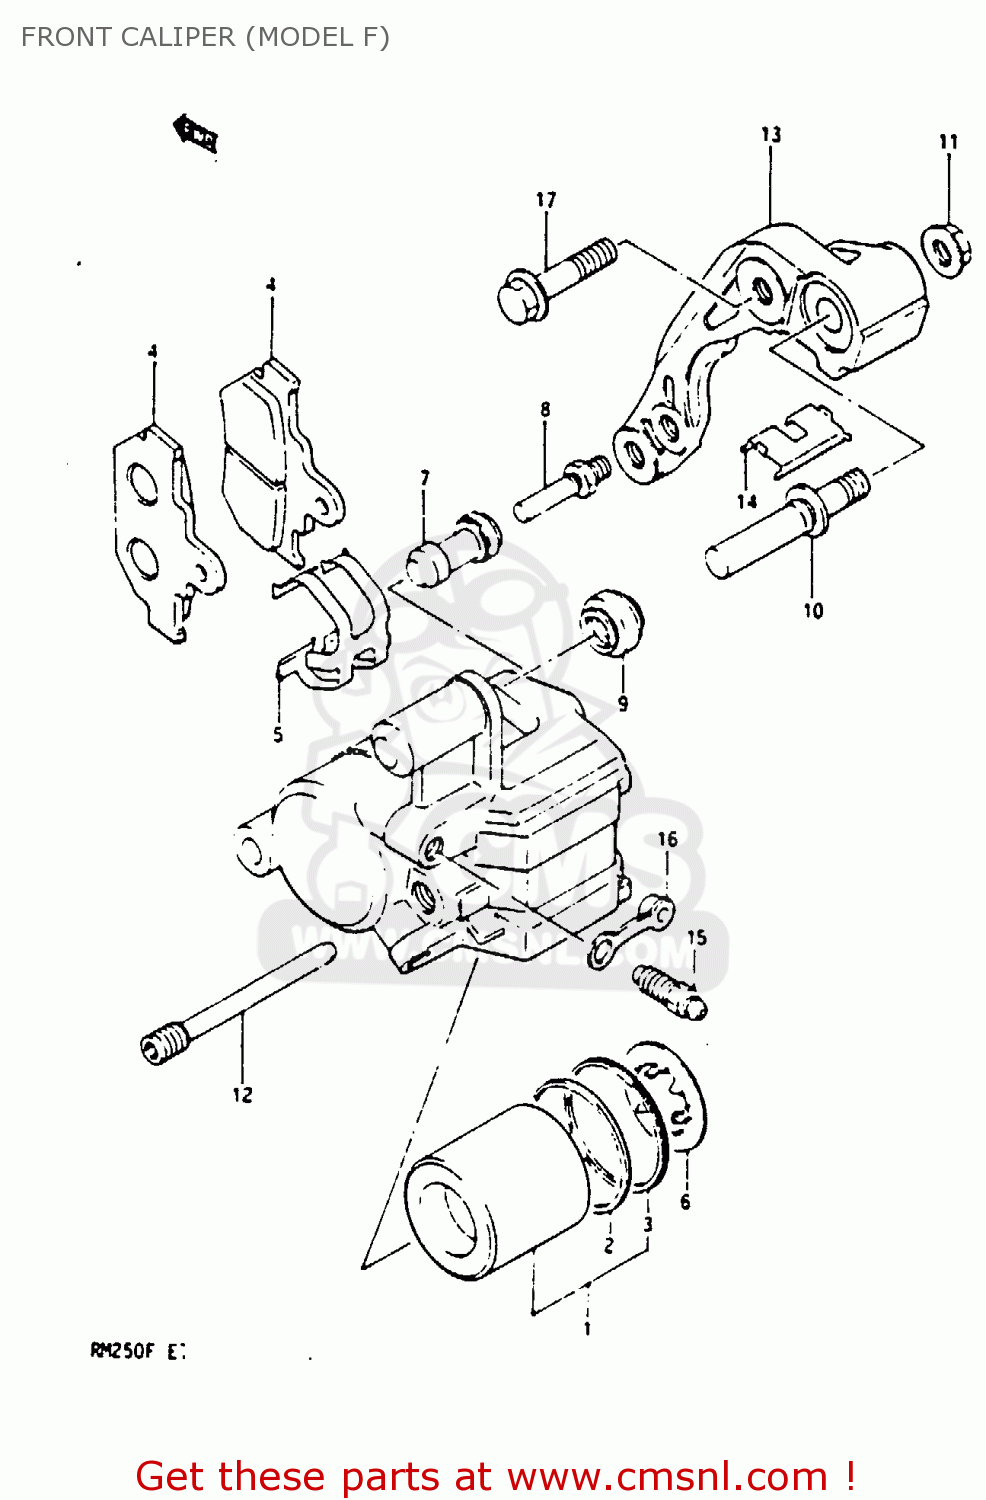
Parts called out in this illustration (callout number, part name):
1	PISTON SET,CALIPERS
2	SEAL,PISTON
3	DUST SEAL,PISTON
4	PAD
5	SPRING
6	SHIM
7	BOOT
8	PIN,BOLT
9	BOOT
10	PIN,SLIDE
11	NUT,SLIDE PIN
12	PIN,HANGER
13	BRACKET
14	RETAINER
15	BLEEDER
16	CAP,BLEEDER
17	BOLT
